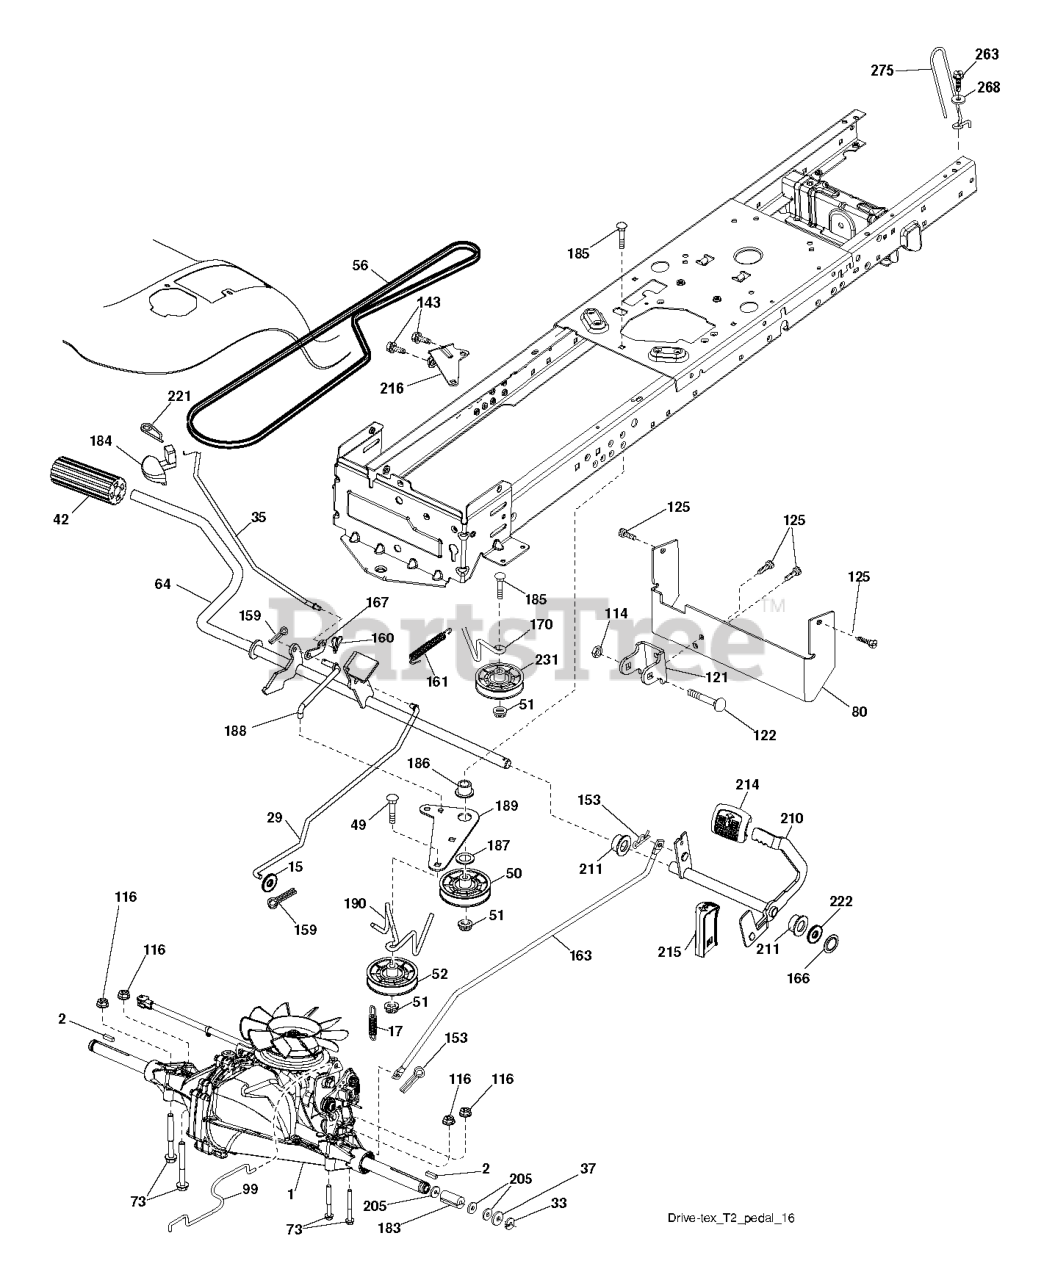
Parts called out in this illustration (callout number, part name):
2	SQUARE KEY
15	WASHER
17	SPRING.BRAKE.HG3000/3500
29	ROD.BRAKE.T2.TEX
35	ROD.CNTRL.PARK.PREDATOR.LT.TEX
42	PEDAL COVER T
50	IDLER.FLAT.910.OFFSET
51	NUT LOCK FLG 3/8-16 UNC
52	IDLER.V-GROOVE.910.OFFSET
64	SHAFT.ASM.PEDAL.BRK.CNTR
73	BOLT HEX 5/16-18 GR 5
80	RP.STRAP.TORQUE.FS.T2
99	ROD.ASM.BYPASS.SPRING.T2.FS
114	NUT.71038.31-18.HEX.NYLOCK
116	NUT LOCK HEX FLANGE 5/16-18
121	BRACKET STRAP TORQUE
122	BOLT.5/16-18X2.5
125	SCREW
143	Screw 5/16-18 x 1/2 Hex, Self Tapping 5/16-18 x 1/2
153	RETAINER M
159	COTTER PIN
160	RETAINER CLIP
161	SPRING, RETURN LT
163	ROD.CONTROL.PCH.T2.TEX
166	NUT.PUSH.625.2006
167	LATCH.BRAKE.SPRING
170	KEEPER.CENTER SPAN.1.688
183	SPACER, AXLE PVST
184	HANDLE PARKING BRAKE
186	SPACER.RETAINER
187	WASHER 12/32X2X10GA
188	RP.LINK.CLUTCH.GROUND.DRIVE
189	BELLCRANK.GROUND.DRIVE.TEX.
190	KEEPER.BELLCRANK.DRIVE
210	ROCKER.ASM.PEDAL.CONTR
211	BEARING.NYLON
214	PEDAL.FORWARD.TEX.GT.4
215	PEDAL RUBBER REVERSE
216	BRACKET.PULLEY.IDLER.W/TEX
221	RETAINER.SPRING.CLIP.H
222	WASHER 21/32 X 1-1/4 X 10 GA.
231	IDLER.V-GROOVE.1.688.OFFSET
263	SCREW, 3/8-16X3/4
268	WASHER
275	GUARD MUFFLER
